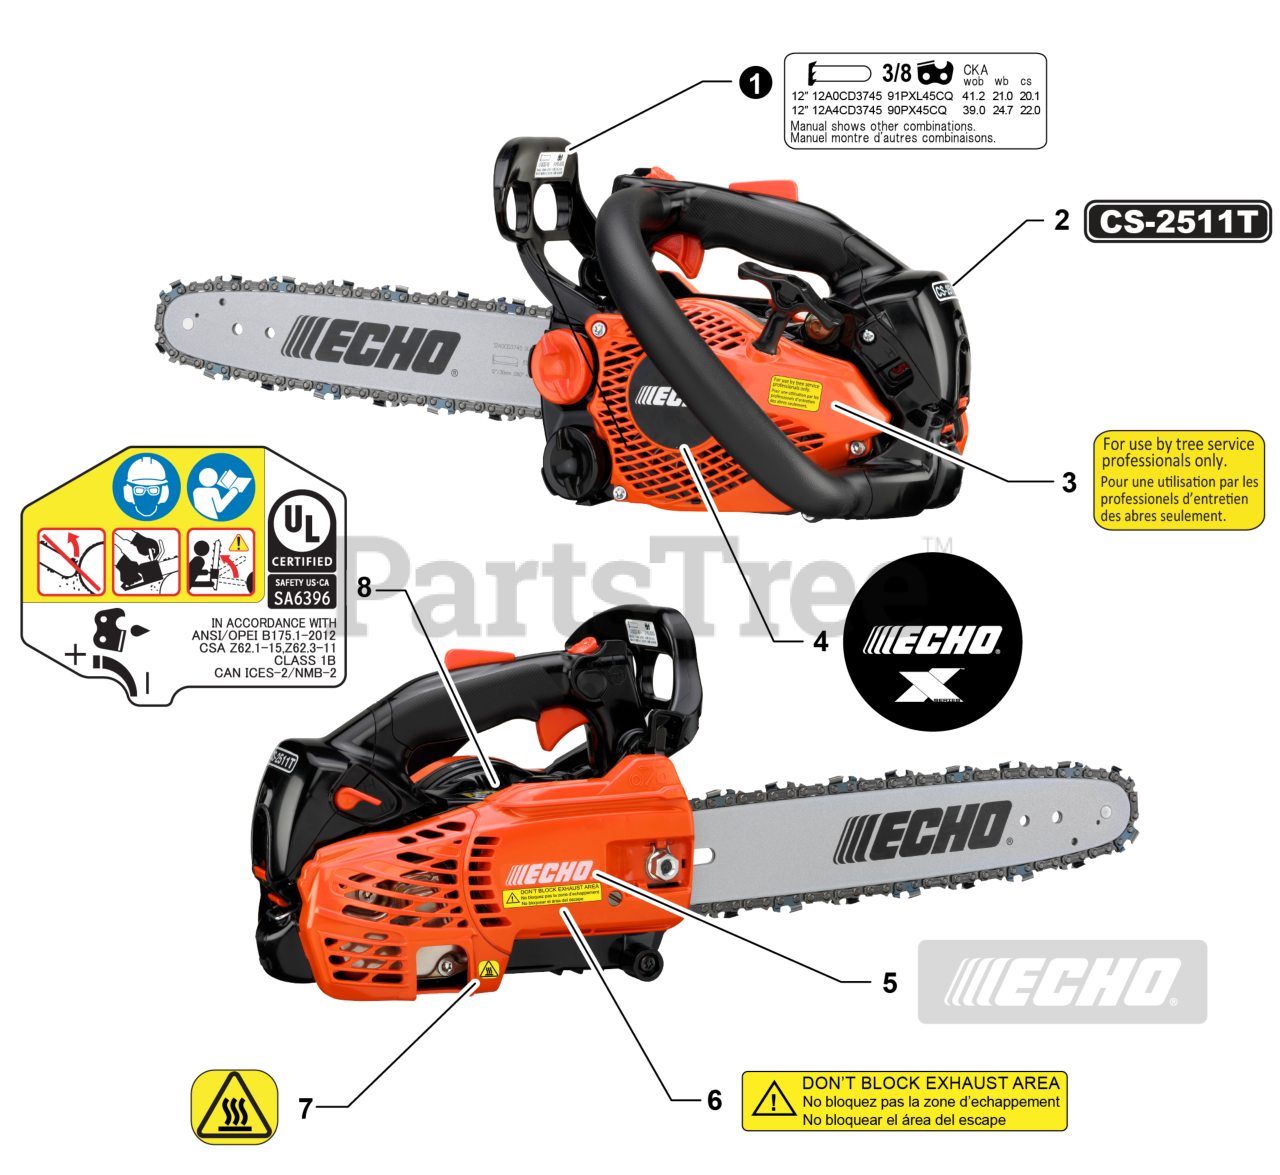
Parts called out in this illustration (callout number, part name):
1	LABEL - BAR & CHAIN
2	LABEL - CS-2511T
3	LABEL - CAUTION - PROFESSIONALS ONLY
4	LABEL - ECHO
5	LABEL - ECHO
6	LABEL - CAUTION - DON'T BLOCK EXHAUST AREA
7	LABEL - CAUTION - HOT
8	LABEL - CAUTION
